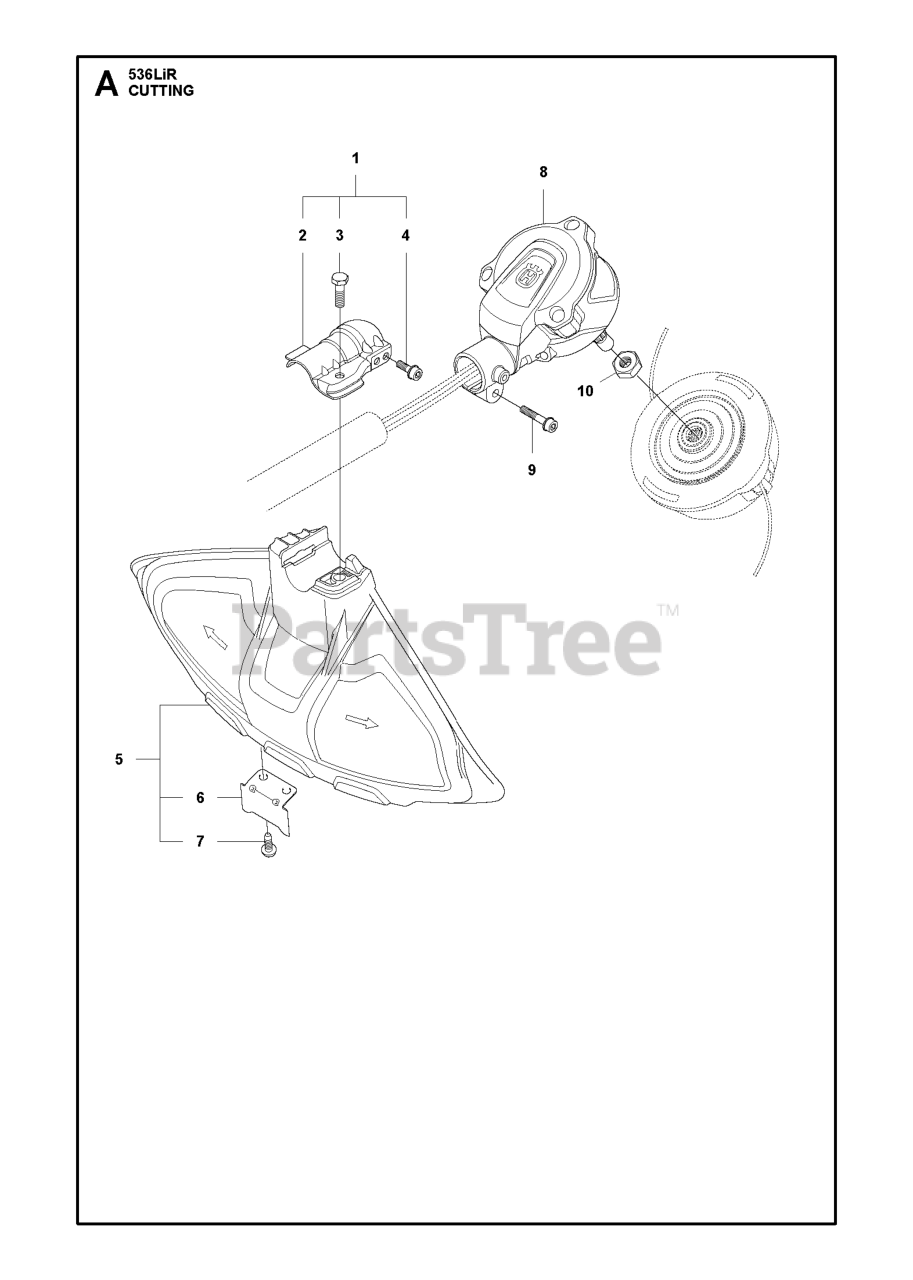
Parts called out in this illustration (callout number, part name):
1	CLAMP
2	RP BRACKET TRIMMER GUARD
5	TRIMMER SHIELD ASSY
6	LINE LIMITER
8	MOTOR CPL.
